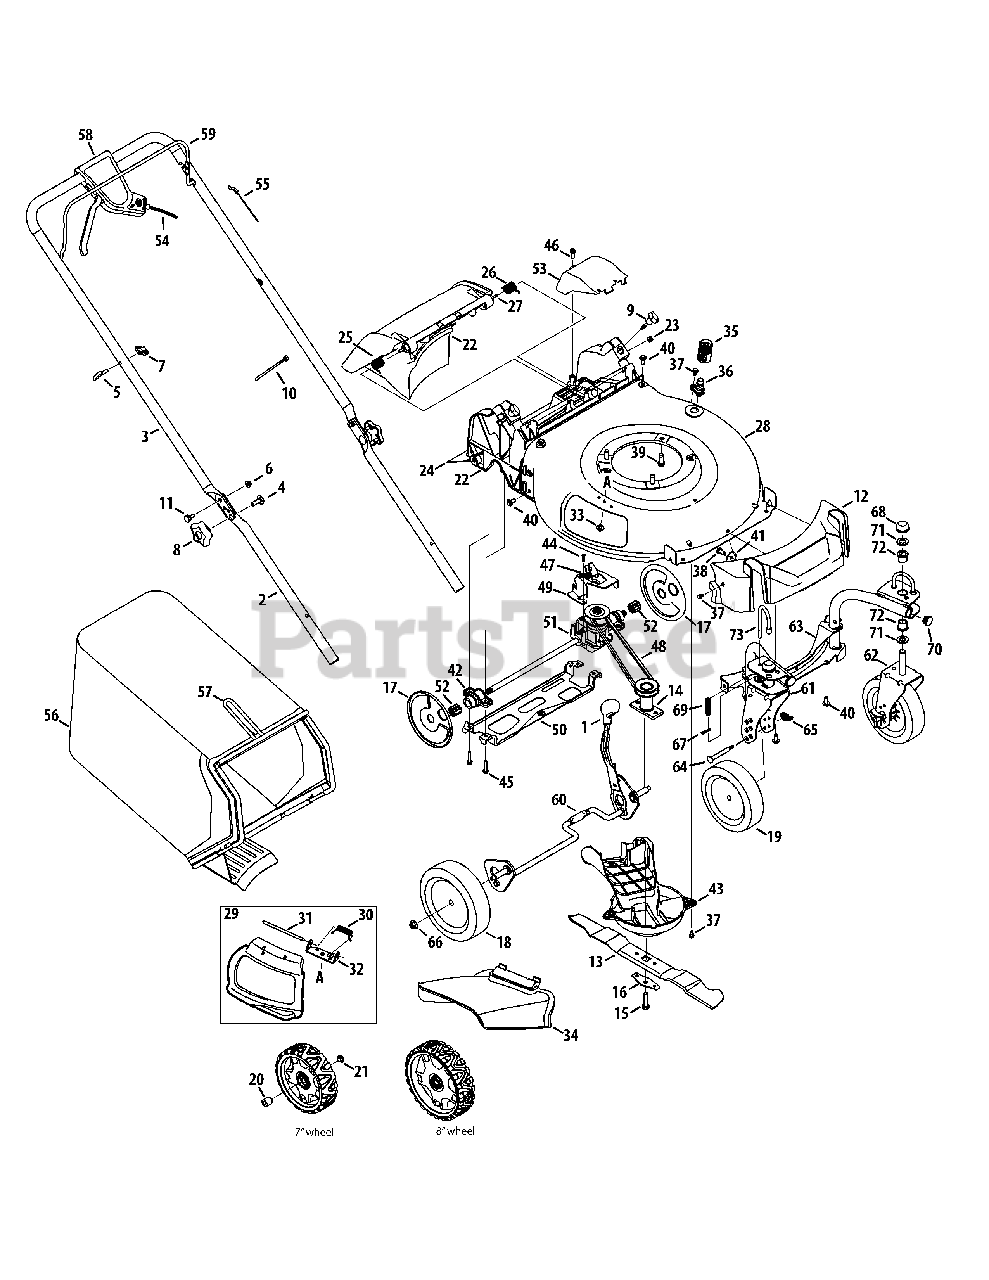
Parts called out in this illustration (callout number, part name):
1	Adjustment Lever Knob
2	Lower Handle
4	Carriage Screw ,5/16-18
5	Rope Guide
6	Nut, Flange Lock, 1/4-20
8	Wing Knob
9	Wing Nut
10	Cable Tie
11	Shdr. Screw, .375 x .126 x 1/4-20
12	Front Cover
13	Mulching Blade
14	Blade Adapter
15	Screw, 3/8-24 x 1.50
16	Blade Bell Support
17	Wheel Dust Cover
18	Rear Wheel, 8 x 2
19	Front Wheel, 7 x 2
20	Caster Hub, Long
21	Caster Hub, Short
22	Rear Discharge Door Assembly
23	Nut, Sq., 1/4-20
24	Trail Shield
25	Torsion Spring - RH
26	Torsion Spring - LH
27	Pivot Rod
29	Mulch Plug (Incl. 30-32)
30	Torsion Spring
31	Hinge Pin
32	Chute Deflector Bracket
34	Side Discharge Chute
35	Water Nozzle Adapter
36	Water Nozzle
37	Shoulder Screw, 1/4-20 x 0.50
38	Self Tapping Screw, 5/16-18 x .750
39	Screw, tt, 3/8-16 x 1.00
40	Screw, 5/16-14 x .750
41	Washer, Flat, .330 x 1.25 x .06
42	Bearing Assembly
43	Engine Baffle
44	Screw, Hex Washer, .159 x .43
45	Screw, 1/4-15 x 1.25
46	Screw, 1/4-15 x .750
47	Exten. Spring, 2.405
48	V-Belt
49	Transmission Bracket
50	Rear Support Bracket
51	Transmission Assembly
52	Spur Gear, 10T
53	Transmission Cover
54	Variable Speed Cable
55	Control Cable (Honda)
56	Grass Bag (Honda)
57	Grass Catcher Frame
58	Control Lever Assembly
58	Lever, Engage
58	Squeeze Box cover
59	Blade Control
60	Rear Axle Assembly
61	Caster Bracket Assembly, RH
62	Caster Bracket Assembly, LH
63	Caster Bracket Assembly
64	Caster Axle, .374 Dia. x 2.59
65	Wing Nut, 1/4-20 w/Bell Washer
66	Flange Lock Nut, 3/8-16
67	Cotter Pin, .072 Dia. x 1.13 Lg.
68	Push Cap, 5/8
69	Compr. Sprng., .531 OD x 1.75 Lg
71	Flat Washer, .640 x 1.12 x .125
72	Flange Bearing, .631 ID
73	Lock Pin: Front Wheel
